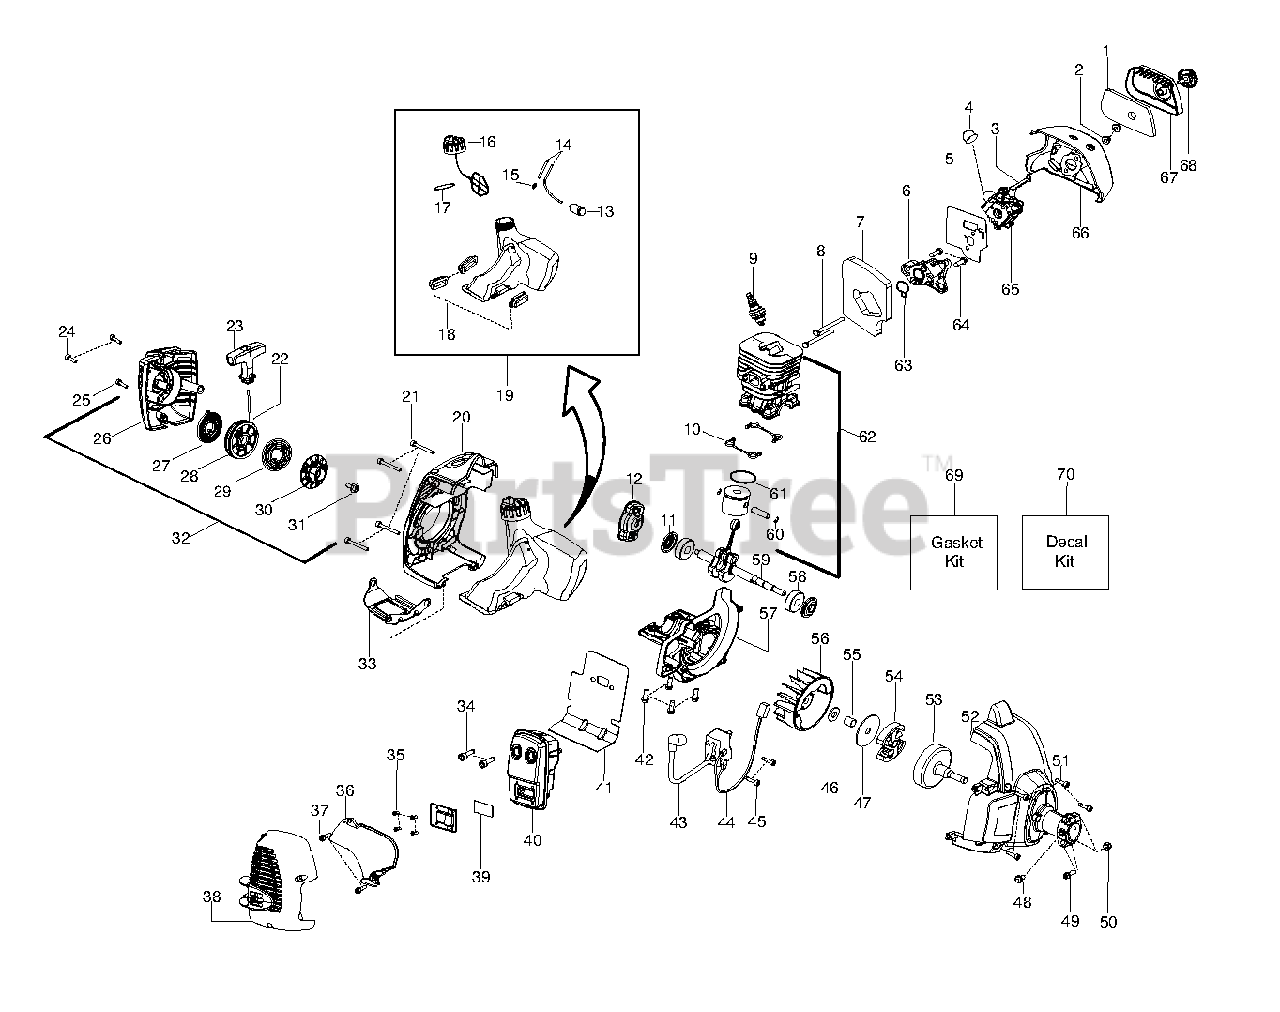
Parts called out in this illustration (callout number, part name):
1	FILTER AIRBOX
3	CHOKE LEVER
4	PURGE BULB ZAMA
5	KIT GASKET CARB 28CC
6	CARB ADAPTOR
7	KIT GASKET 28CC
8	BOLT CARB ADAPTOR
10	KIT GASKET 28CC
11	KIT GASKET 28CC
12	STARTER PAWL BRIDGE
13	FUEL PICK-UP ASSY
14	KIT-LINE(FUEL)
15	FUEL LINE FITTING
16	ASSY - FUEL CAP W/RETAINER
17	KIT GASKET 28CC
18	ISOLATOR FUEL TANK
19	KIT FUEL TANK ASSY
20	SHROUD REAR
23	HANDLE - STARTER
24	SCREW M5-0.8X30MM
25	SCREW M4 X 1.75 PT 16MM
26	STARTER HSG W/EYELET
27	KIT STARTER SPRING
28	KIT STARTER PULLEY
29	SPRING - DRIVER
30	DRIVER PULLEY
32	ASSY STARTER HSG
33	PLATE WEAR
34	BOLT MUFFLER
35	SCREW-6-19X5/16PLAST PA
36	SHIELD HEAT
37	SCREW M4 X 1.75 PT 16MM
38	KIT MUFFLER GUARD
39	KIT SPARK ARRESTOR SCREEN
40	KIT MUFFLER W/CATALYST
41	KIT GASKET 28CC
42	B0LT, C/SHAFT 36/41
43	IGNITION MODULE
44	ASSY MODULE LEAD WIRE
45	SCREW M4 X .70 TT 16MM
46	WASHER CLUTCH
47	WASHER-CLUTCH
48	SCREW-10-16 X 1/2, TYPE 2
49	SCREW-10-24 X 1" (UNC)
50	LOCKNUT-HEX 10-24
51	SCREW M4 X .70 TT 16MM
52	ASSY FAN HOUSING
53	ASSY-CLUTCH DRUM
54	ASSY CLUTCH
55	SPACER FLYWHEEL
57	CRANKCASE CAST LE28
58	BEARING RADIAL BALL (6201)
59	ASSY CRANKSHAFT
60	WRIST PIN RET.
61	RING PISTON
62	KIT PISTON & CYLINDER
63	KIT GASKET 28CC
64	B0LT, C/SHAFT 36/41
65	KIT CARB
66	AIRBOX BLACK
67	COVER AIR BOX
68	ASSY - AIR BOX KNOB
69	KIT GASKET 28CC
